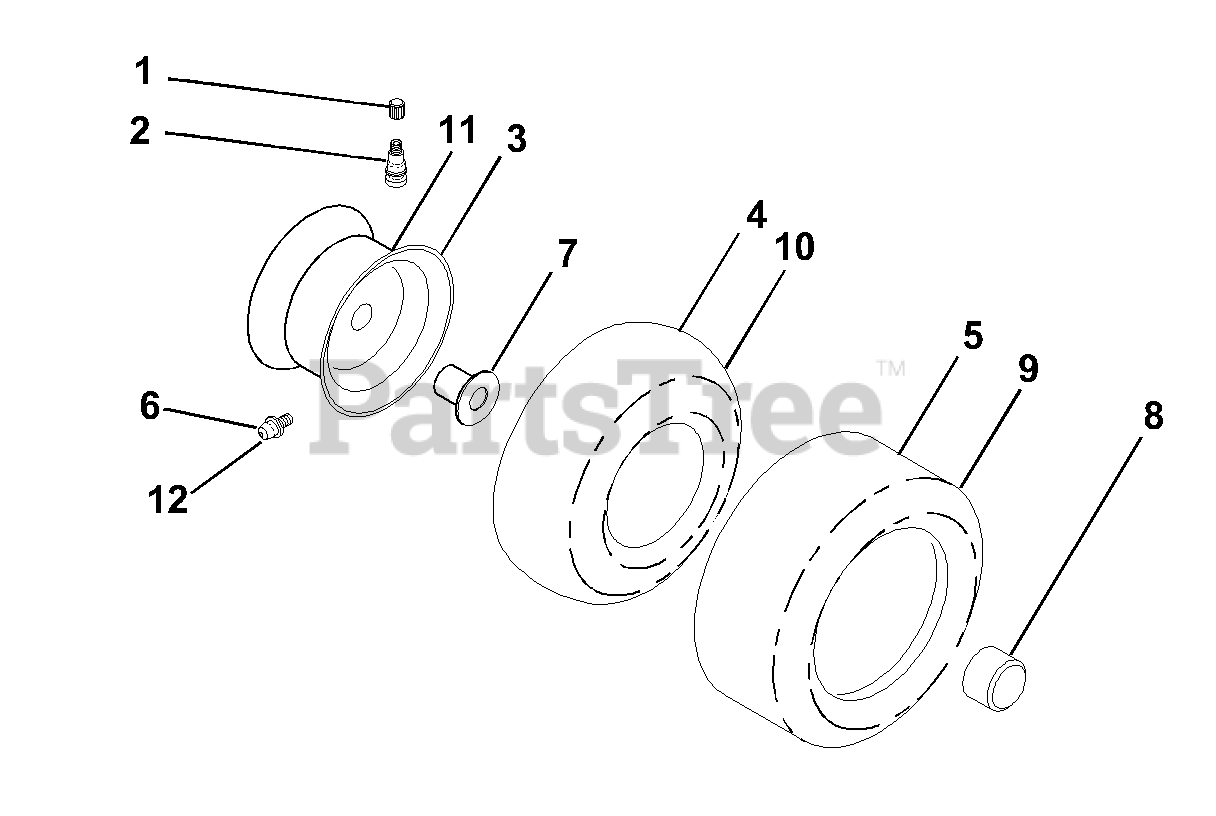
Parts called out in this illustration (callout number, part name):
1	Cap, Valve, Tire
2	Stem, Valve
3	Rim Assembly, Front
4	Tube, Front
5	Tire, Front
6	Fitting, Grease
7	Bearing, Flange
8	Cap, Axle
9	Tire, Rear
10	Tube, Rear
11	Rim Assembly, Rear
12	Fitting, Grease
